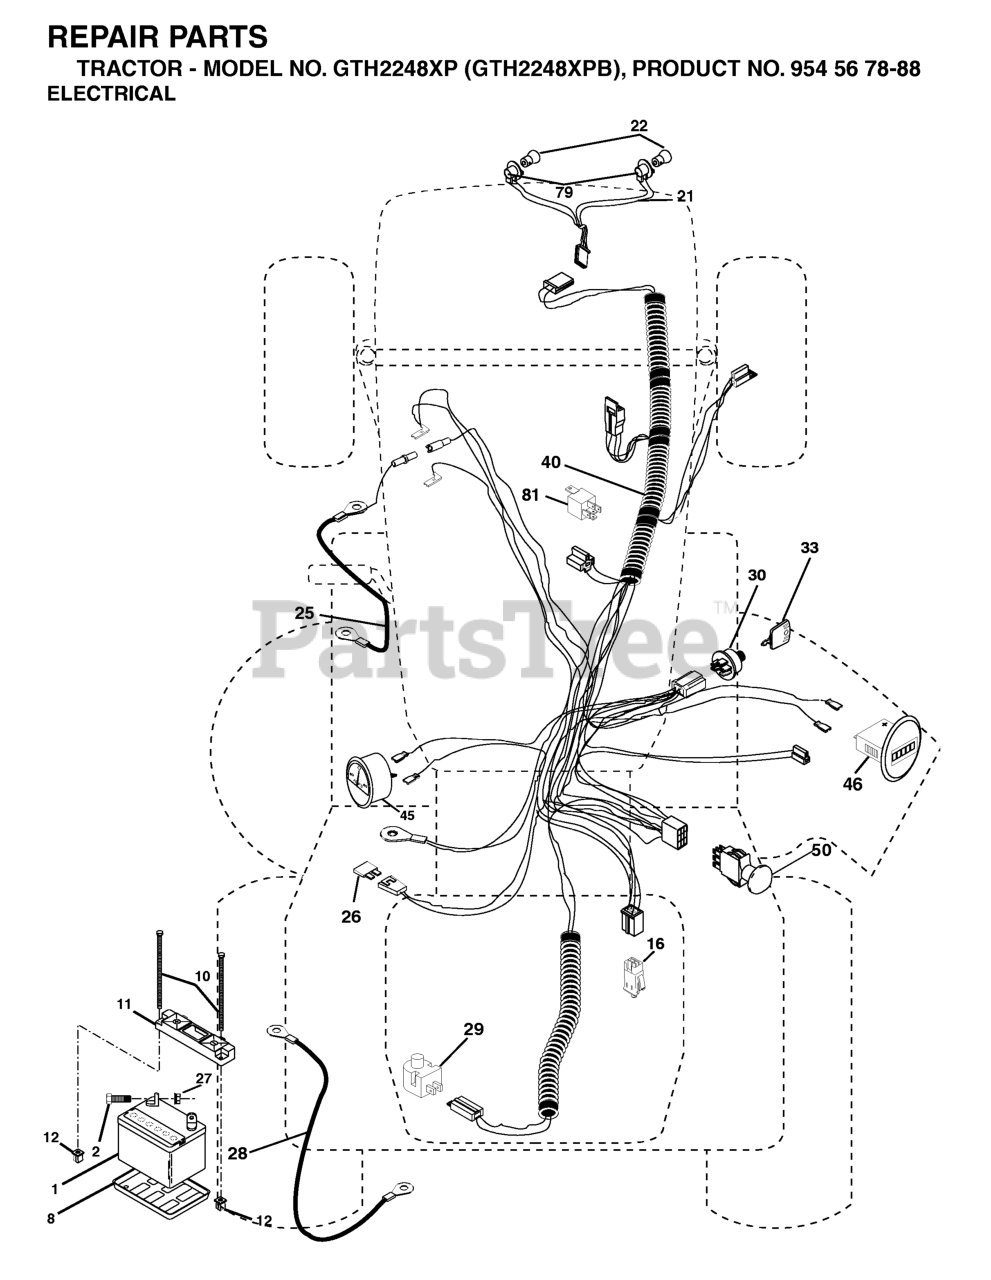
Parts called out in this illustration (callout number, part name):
1	BATTERY 12V .35 AMP
2	BOLT.HEX.1/4.X.3/4.DICHROMATE
8	BATTERY TRAY T
10	BOLT 1/4-20 X 7.5
11	BATTERY HOLDDOWN FRONT MOUNT
12	NUT, PUSH NYLON 1/4" BATTERY
16	SWITCH INTERLOOK PUSH-IN
21	HARNESS.W/LIGHT SOCKET
25	CABLE, BATTERY
27	NUT
28	CABLE, GROUND
29	PLUNGER SWITCH (COLOR:OLIVE)
30	IGNITION SWITCH
33	KEY MLD GEN DELTA
42	COVER.TERMINAL.RED
45	RP AMMETER.ROUND.SILVER.DELTA
46	RP HOURMETER SNAP-IN
50	RP.PTO.SWITCH.8 TERMINAL.BLACK
79	BULB HOLDER ASM.
81	RELAY.ASSY.T
